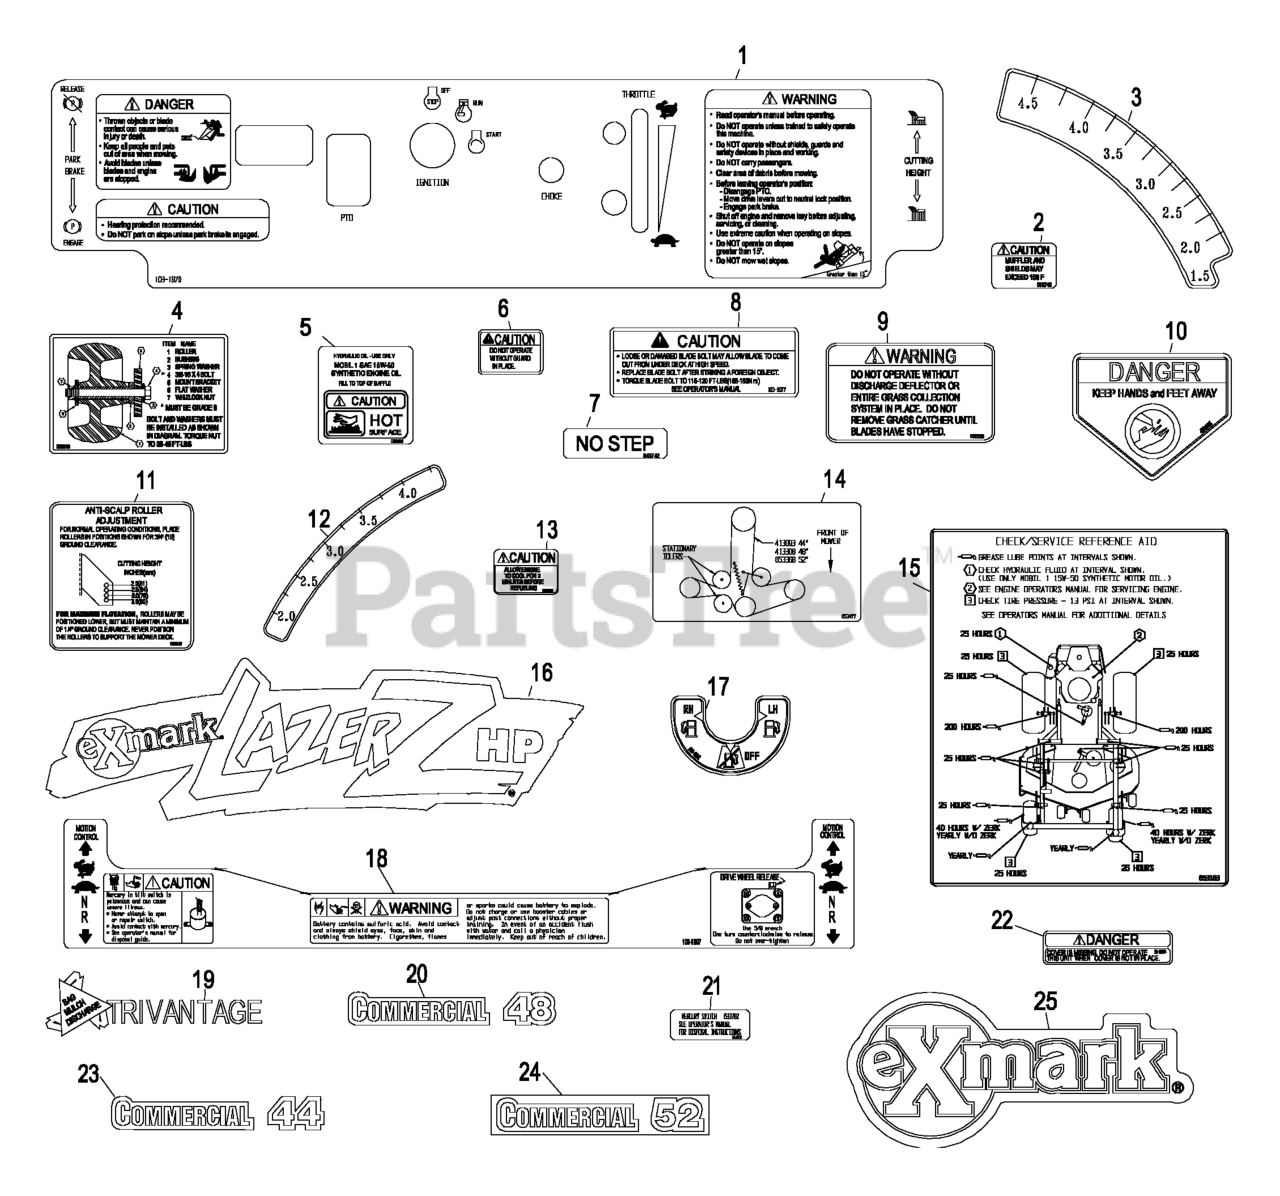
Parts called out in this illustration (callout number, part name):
3	DECAL-DECK HEIGHT, OUTER
4	DECAL,ROLLER MOUNTING
6	DECAL-GUARD
7	DECAL,NO STEP
8	DECAL,BOLT TORQUE
9	DECAL-WARNING, DISCHARGE
10	DECAL-DANGER
11	DECAL,ANTISCALP
12	DECAL-DECK HEIGHT, INNER
17	DECAL-VALVE, FUEL
20	DECAL,COMMERCIAL 48
21	DECAL-SWITCH, MERCURY
22	DECAL-COVER, MISSING
23	DECAL,COMMERCIAL 44
24	DECAL,COMMERCIAL 52
